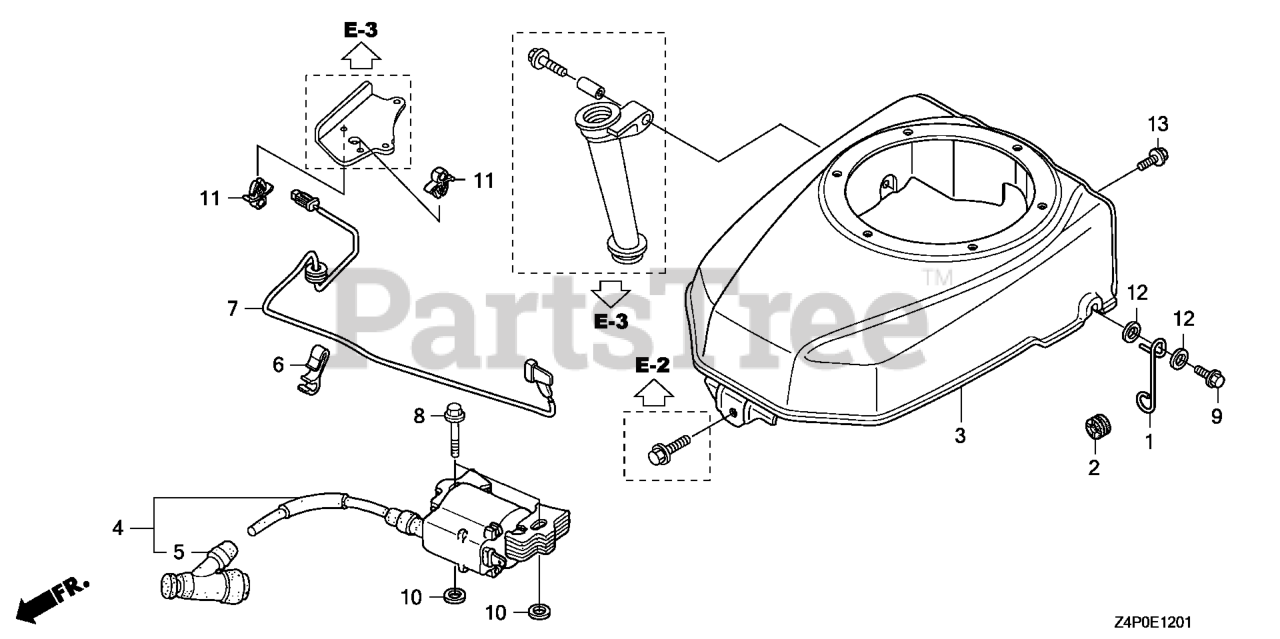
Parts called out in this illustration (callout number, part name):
1	STAY, FUEL TUBE
2	RUBBER, RADIATOR MOUNTING
3	COVER, FAN *R280* (POWER RED)
3	COVER, FAN *NH1* (BLACK)
4	COIL ASSY., IGNITION & CAP ASSY. NOISE SUPPRESSOR (TOYO)
8	BOLT, FLANGE (6X28) (CT200) Use up to Engine SN 1530314.
9	BOLT, FLANGE (6X16)
10	WASHER, PLAIN (6MM)
12	WASHER, PLAIN (6MM)
13	BOLT, FLANGE (6X12) Use up to Engine SN 1543277.
